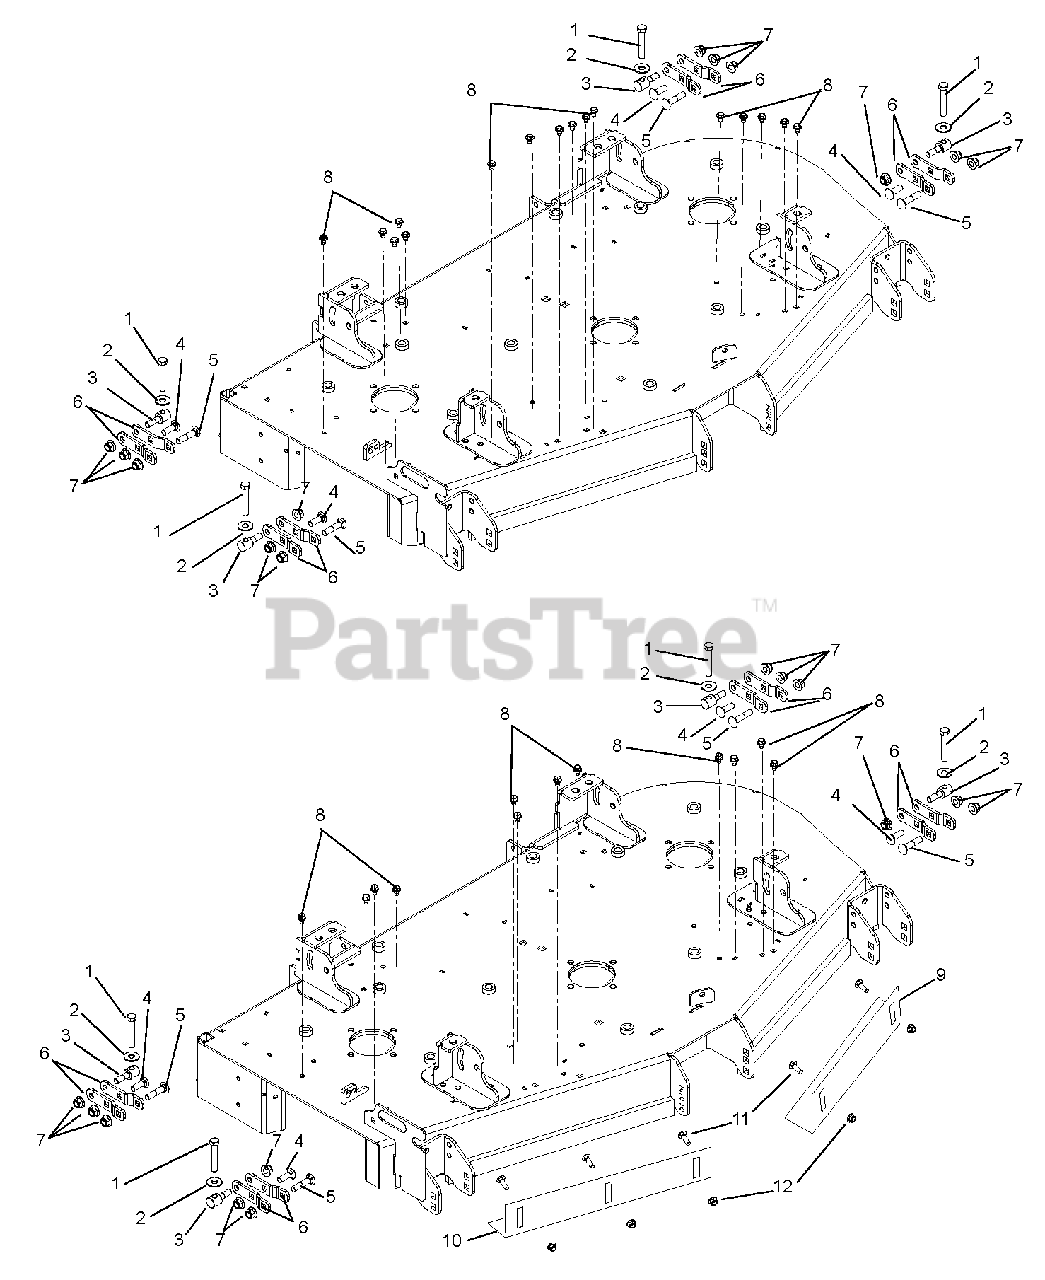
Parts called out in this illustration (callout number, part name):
1	Bolt, Hex .50-13 x 3.00 Grade 5 Full Thread
2	Washer, Flat Steel .563 x 1.38 x .109
3	Trunnion, .50-13
4	Bolt, Round Head Square Neck .50-13 x 1.50 Grade 5
5	Bolt, Round Head Square Neck .50-13 x 2.25 Grade 5
6	Deck Leveling Bracket – Black
7	Nut, Locking Nyloc Flange .50-13
8	Screw, Tapping .38-16 x .50 Hex Washer Head (992201, 203, 204, 198)
9	Baffle, Vacuum Left Hand 52" (992200, 205, 197)
10	Baffle, Vacuum Right Hand 52" (992200, 205, 197)
11	Bolt, Round Head Square Neck .31-18 x .75 Grade 5
12	Nut, Lock Nyloc .312-18
